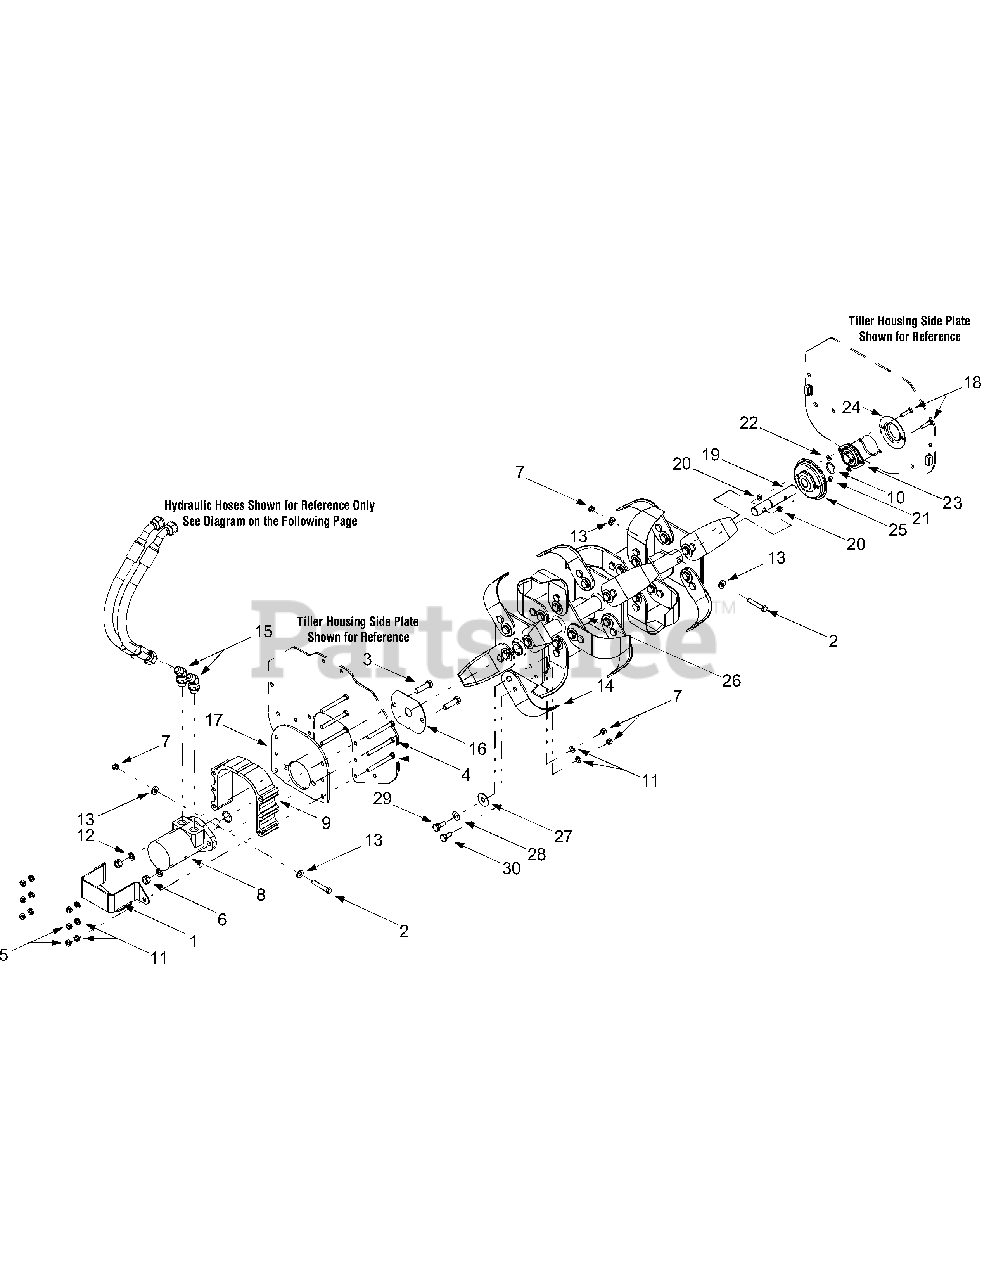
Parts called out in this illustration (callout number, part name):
3	Hex Cap Screw, 1/2-13 x 1.75
4	Hex Cap Screw, 3/8-16 x 3.5
5	Hex Lock Nut, 3/8-16
6	Hex Lock Nut, 1/2-13
7	Hex Lock Nut, 3/8-24
8	Eaton Hydraulic Motor
8	Key, Hyd Motor Shaft
9	Hydraulic Motor Mounting Spacer
10	O Ring Seal
11	Lock Washer, 3/8
12	Lock Washer, 1/2
13	Flat Washer, .406 x .875 x .105
15	45° Hydraulic Adapter, 7/8
19	Tine Shaft
20	Hex Lock Nut, 5/16-18
21	Hex Nut, 5/16-18
22	Lock Washer, 5/16
23	Flange Bearing, 1.0
28	Belleville Washer
29	Shoulder Screw, .49 x .21, 3/8-24
30	Shoulder Screw, .49 x .34, 3/8-24
